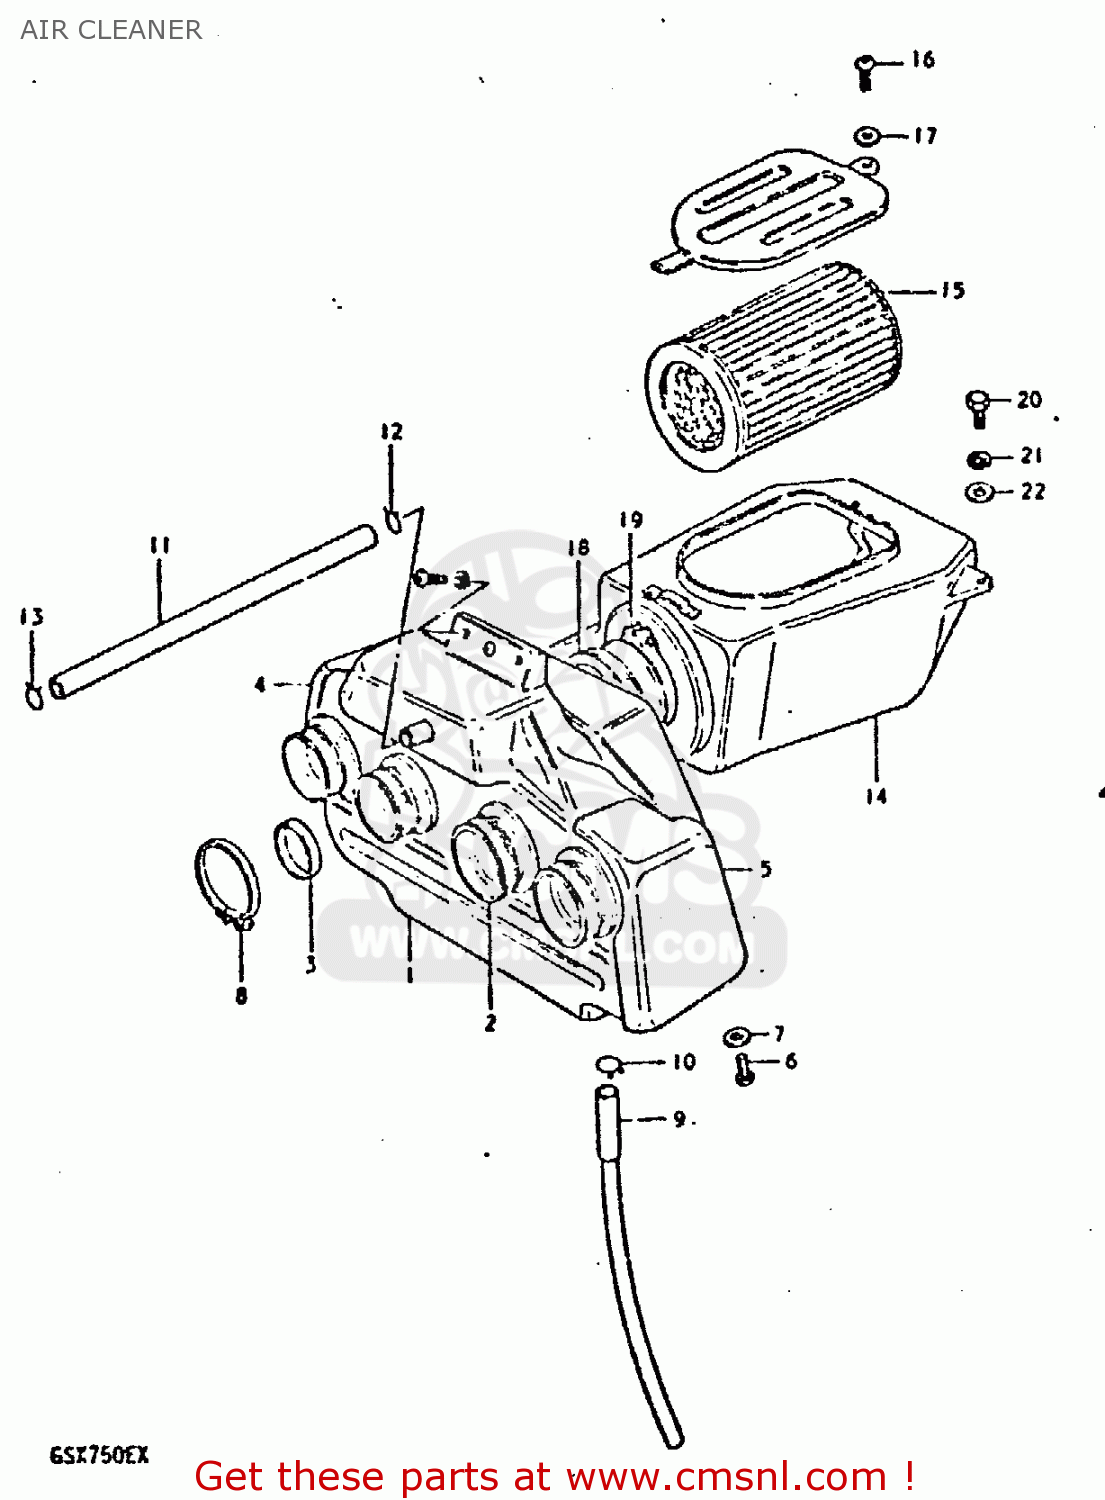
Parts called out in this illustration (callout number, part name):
1	CASE COMP,AIR CLEANER
2	TUBE,AIR CLEANER OUTLET
3	RING,CARBURETOR AIR IN
4	COVER,AIR CLEANER,RIGHT
5	COVER,AIR CLEANER,LEFT
6	SCREW
7	WASHER
8	CLAMP
9	DRAIN TUBE
10	CLIP
11	TUBE,BREATHER
12	CLIP,BREATHER HOSE
13	CLIP
14	CLEANER ASSEMBLY,AIR
15	FILTER,AIR CLEANER
16	SCREW
17	WASHER
18	JOINT,HOSE AIR CLEANER
19	CLAMP
20	BOLT
21	LOCK WASHER
22	WASHER 6MM
